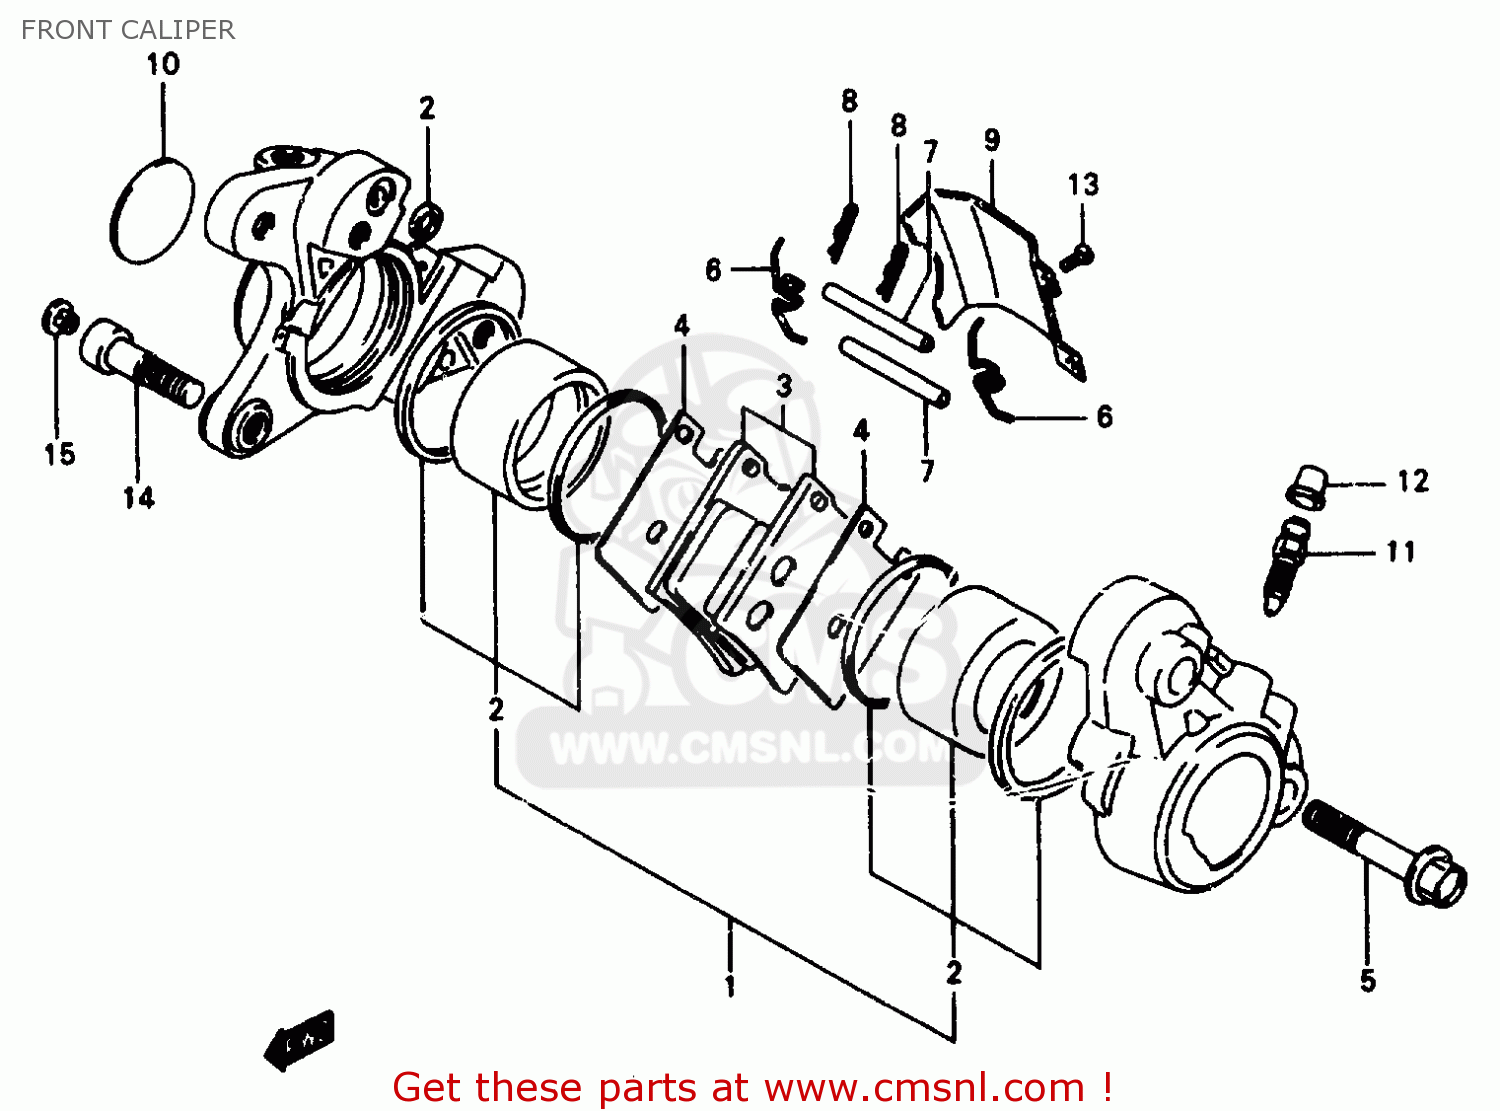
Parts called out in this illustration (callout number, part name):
1	PISTON SET
2	SEAL SET,PISTON
3	PAD SET (NAS)
4	SHIM,PAD
5	BOLT,HOUSING
6	SPRING
7	PIN,PAD
8	CLIP,PAD PIN
9	COVER,CALIPER HOUSING,DUST
10	CAP,CALIPER
11	BLEEDER
12	CAP,BLEEDER PLUG
13	SCREW,CALIPER COVER(4X6)
14	BOLT(10X33)
15	CAP(OD:12)
